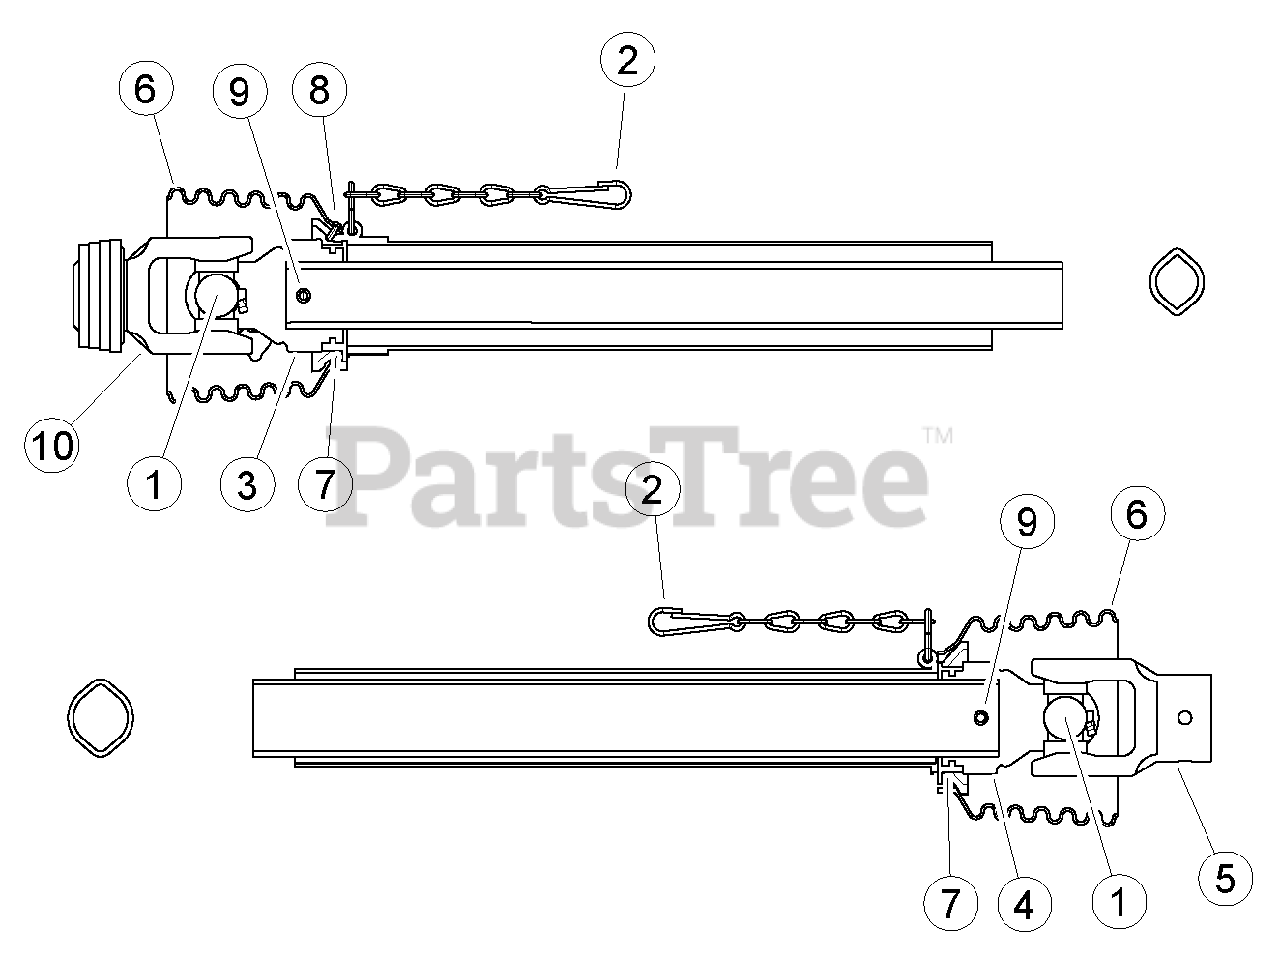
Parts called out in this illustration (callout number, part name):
1	KIT, CROSS & BEARING W-2400
2	CHAIN, SAFETY
3	YOKE, INBOARD 1B
4	YOKE, INBOARD 2A
5	YOKE, 1-1/2" RND
6	CONE, 6 RIB SAFETY
7	RING, SC25 BEARING
8	SCREW, WS365305
9	PIN, M10 X 80 SPRING
10	YOKE, 1-3/8-6 SPLINGE ASGE
